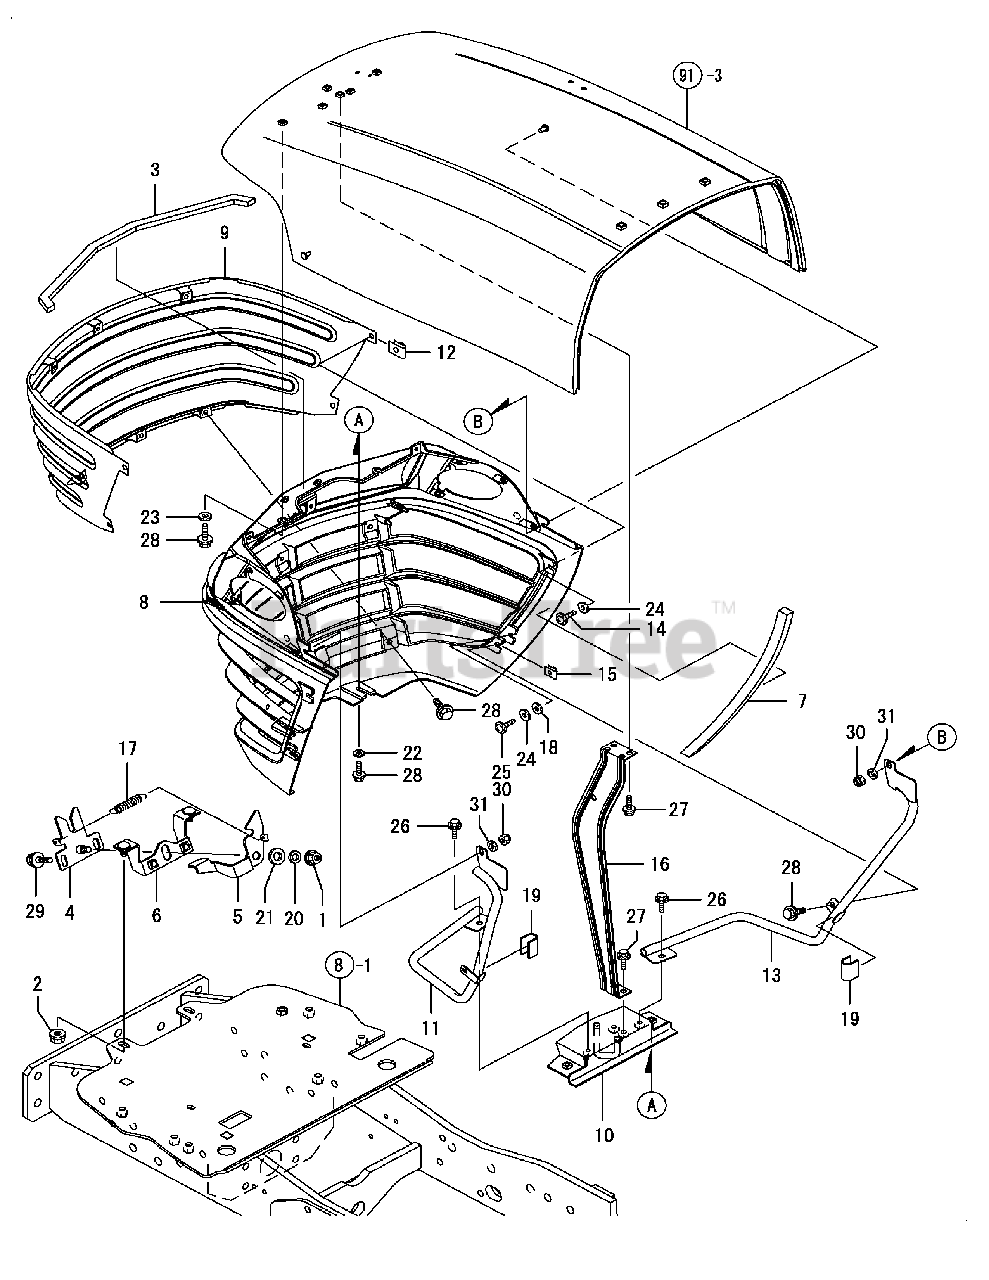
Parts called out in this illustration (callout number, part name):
1	NUT W/WASHER 8
2	NUT W/WASHER 8
3	URETHANE, GRILLE
5	LEVER, GRILLE LOCK
6	PLATE, BASE LOCK
7	SEAL, GRILLE SIDE
9	NET ASSY, GRILLE
10	STAY ASSY, LOCK
11	FRAME ASSY, L GRILLE
13	FRAME ASSY, R GRILLE
14	SCREW 5X16
16	STAY, FRONT GRILLE
20	WASHER 8, POLISHED
21	WASHER 12, POLISHED
25	SCREW, 5.0 X 20
26	BOLT M 6X 12 PLATED
27	BOLT M 6X 12 PLATED
28	BOLT M 6X 16 PLATED
29	BOLT M 8X 12 PLATED
30	U-NUT M 6 PLATED
31	WASHER 6, POLISHED
